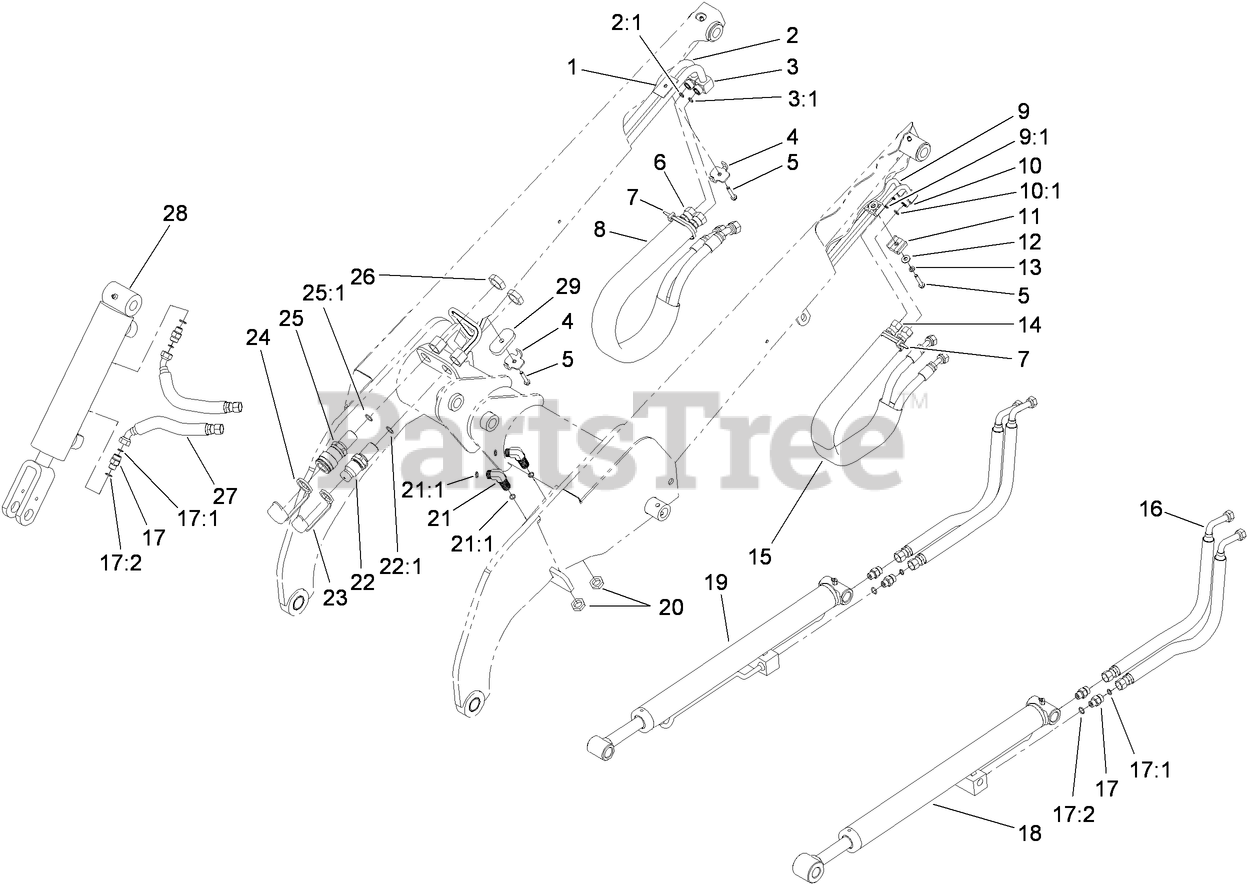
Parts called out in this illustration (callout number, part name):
1	SPACER-HARDLINE
2	HYD TUBE ASM
2:1	O-RING
3	HYD TUBE ASM
3:1	O-RING
4	PLATE-CLAMP, TUBE
5	SCREW-HWH
6	HOSE-HYD
7	TIE-CABLE
8	SLEEVE-PROTECTIVE
9	HYD TUBE ASM
9:1	O-RING
10	HYD TUBE ASM
10:1	O-RING
11	CLAMP-TUBE
12	WASHER-FLAT
13	WASHER-LOCK
14	HOSE-HYD
15	SLEEVE-PROTECTIVE
16	HOSE-HYD
17	FITTING-STRAIGHT
17:1	O-RING
17:2	O-RING
18	LH LIFT CYLINDER ASM
19	RH LIFT CYLINDER ASM
20	NUT-LOCK
21	UNION-BULKHEAD
21:1	O-RING
22	BULKHEAD NIPPLE ASM
22:1	O-RING
23	CAP-DUST, NIPPLE
24	CAP-DUST, COUPLER
25	BULKHEAD COUPLER ASM
25:1	O-RING
26	NUT-LOCK, BULKHEAD
27	HOSE-HYD
28	TILT CYLINDER ASM
29	PLATE-HARDLINE
